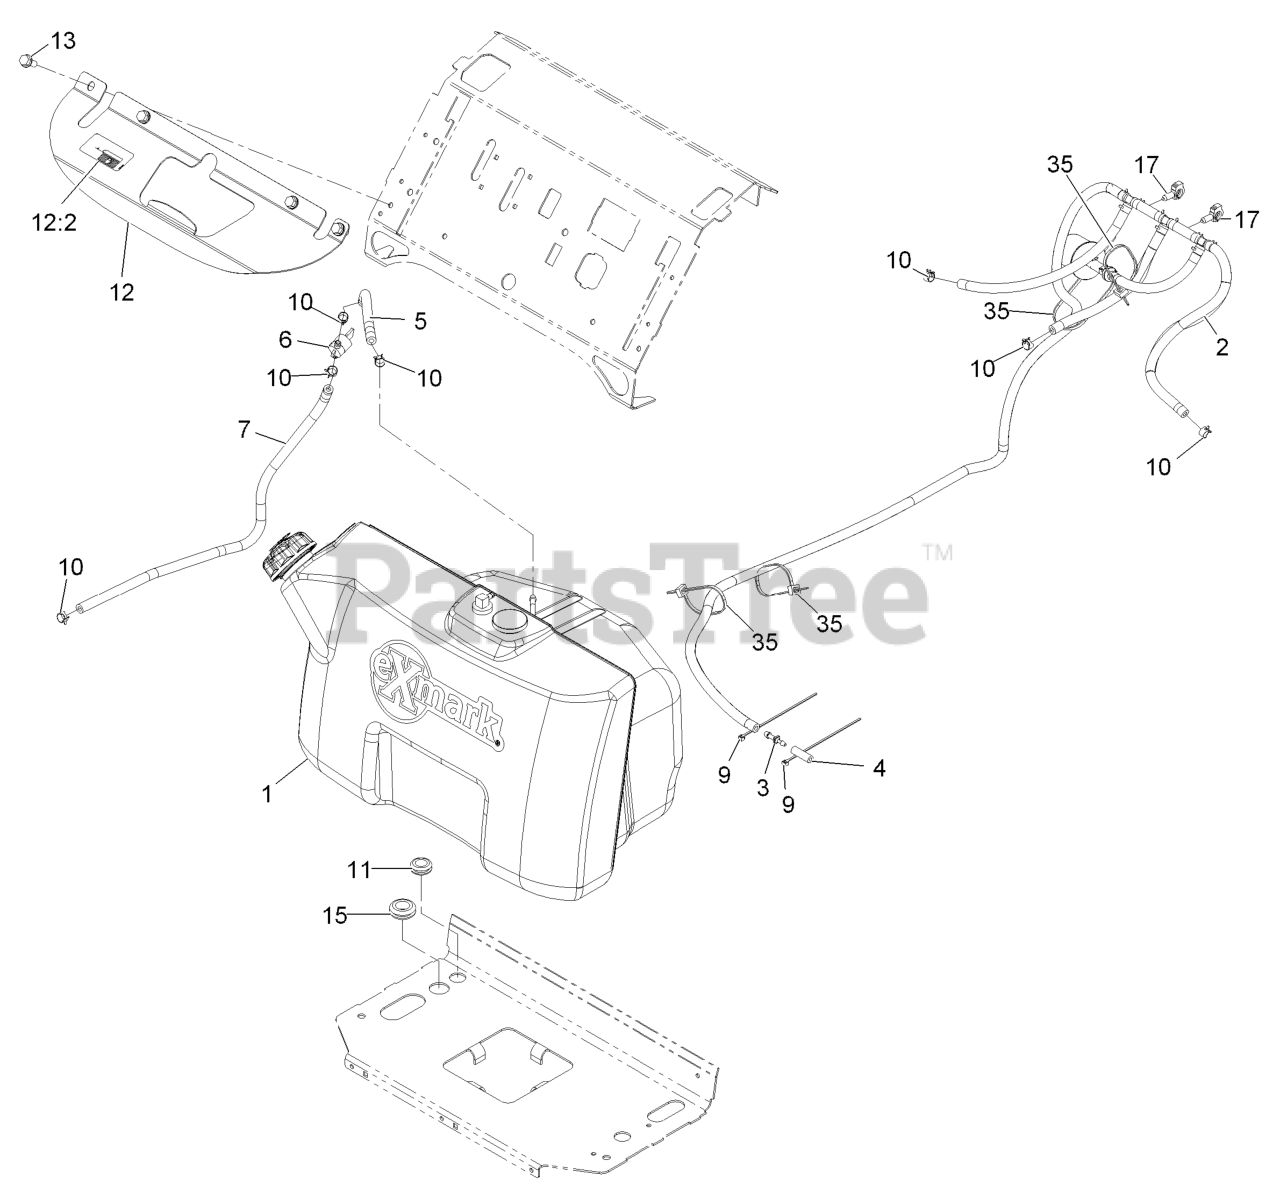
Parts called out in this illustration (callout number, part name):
2	VENT ASM
3	FITTING-STRAIGHT
4	HOSE-FUEL
5	HOSE-FUEL
6	VALVE-FUEL
7	HOSE-FUEL
9	TIE-CABLE
10	CLAMP-HOSE
11	GROMMET
12	BRACKET-TANK
12:2	DECAL-FILL, FUEL
13	SCREW-THD ROLL, HWH
15	GROMMET
17	CLIP-HARNESS
35	TIE-CABLE
